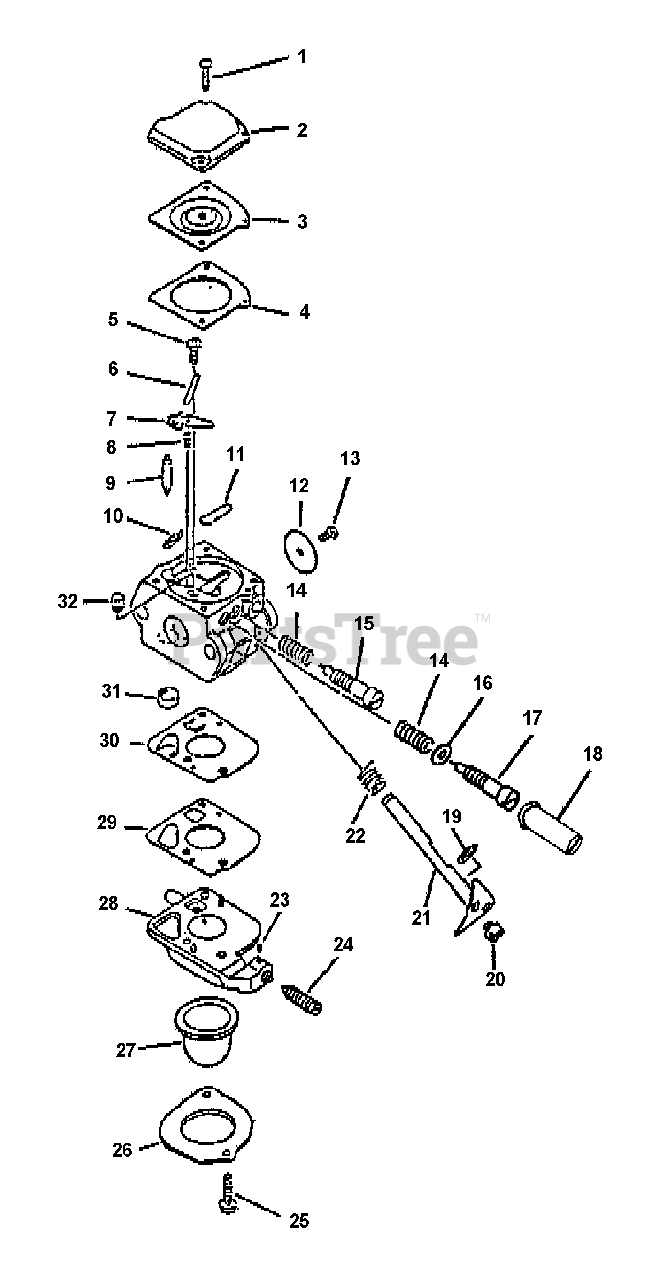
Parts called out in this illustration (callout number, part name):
2	COVER, METERING
3	DIAPHRAGM
4	GASKET, METERING
5	SCREW, METERING LEVER PIN
6	PIN, METERING LEVER
7	LEVER, METERING
8	SPRING, METERING
9	VALVE, NEEDLE
10	RING, RETAINING
11	PLUG, WELCH
12	VALVE, THROTTLE
15	NEEDLE - MIXTURE
17	NEEDLE - HIGH SPEED
18	CAP, LIMITER
19	RING, RETAINING
21	SHAFT, THROTTLE
22	SPRING, RETURN
23	PIECE, FRICTION
24	SCREW, IDLE ADJUST
25	SCREW, RETAINER
26	RETAINER, PURGE BULB
27	BULB, PURGE
28	BASE, PURGE
29	GASKET, PURGE
30	DIAPHRAGM, PURGE
31	STRAINER
32	NOZZLE, CHECK VALVE
